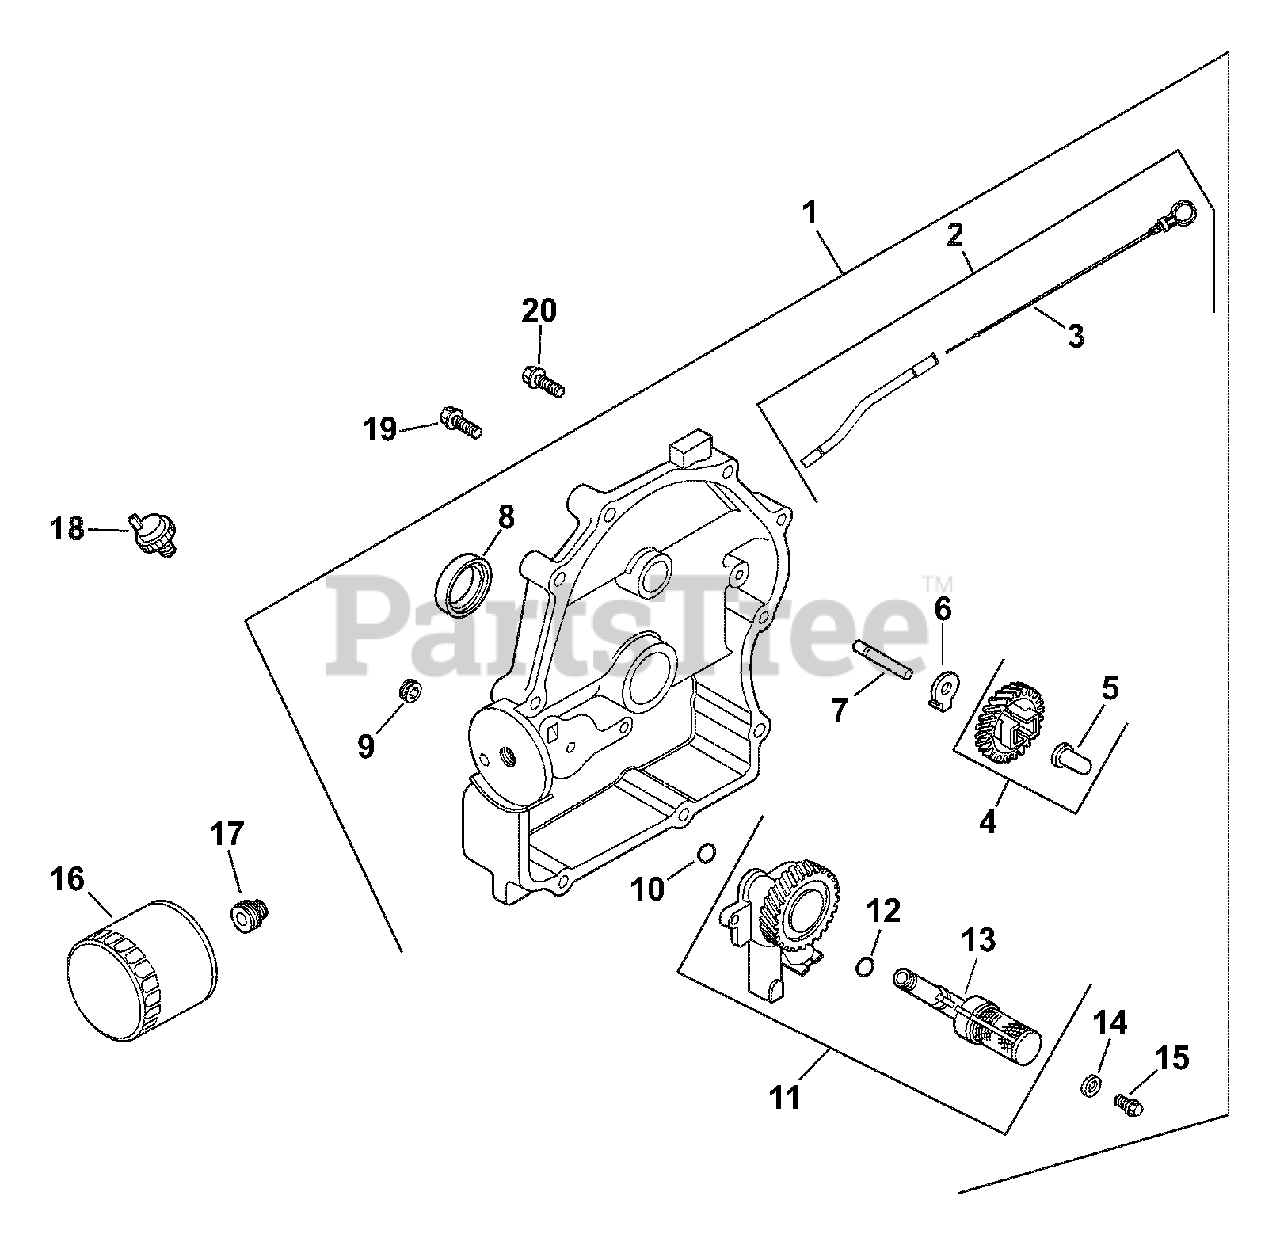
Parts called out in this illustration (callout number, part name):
1	Plate, closure assembly
2	Kit, tube w/dipstick
4	Kit, governor gear
5	Pin, governor regulating
7	Shaft, governor gear
8	Seal, oil (PTO end)
9	Plug, pipe 1/8"
11	Oil pump assembly
12	O-Ring, oil pick-up
13	Pick-up, oil
14	Washer, plain 6 mm
15	Screw, hex. flange M6x1.0x25
16	Filter, oil
17	Nipple, oil filter
18	Switch, pressure
19	Screw, hex. flange M8x1.25x45
20	Screw, hex. flange M8x1.25x45
